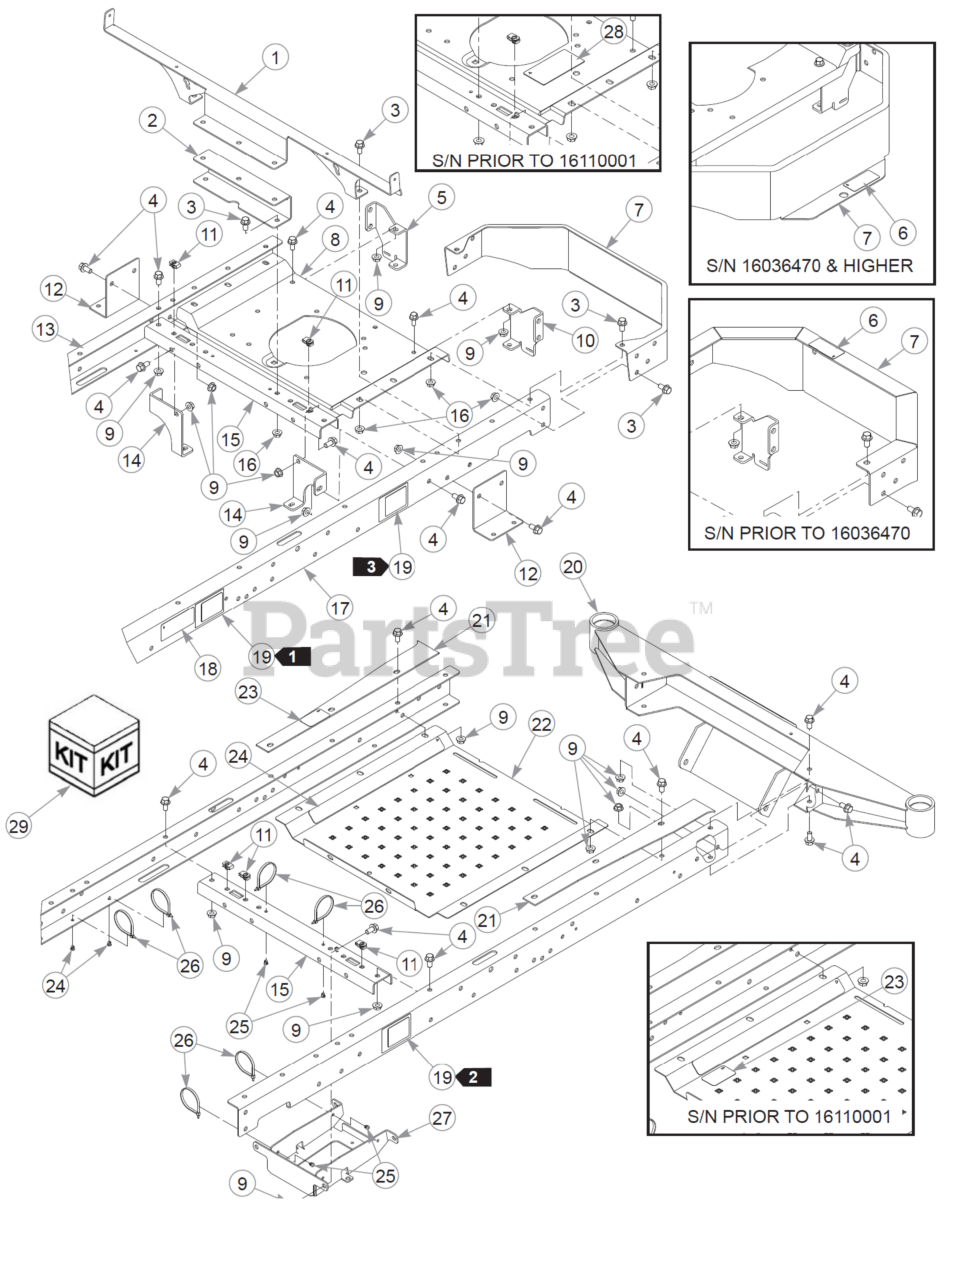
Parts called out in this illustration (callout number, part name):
1	SEAT SUPPORT
2	SPRING SUPPORT
3	CS .375-16X0.75 HXF G5ZN
4	KIT SWITCH
5	ORDER 125255 KIT
6	DECAL, HOT
7	S/C TO 556499
8	SVC, ENGINE PLATE
9	NT .375-16 HXFLK PLN
10	ORDER 125255 KIT
11	CN .250-20X .150 MAX THK
12	ORDER 125255 KIT
13	SVC, RS FRM CHNL
14	ORDER 125255 KIT
15	SVC, CROSS SUPPORT
16	NT .375-16 FLKG5
17	SVC, LS FRM CHNL
18	DECAL, ENGINE COMPART
19	Not Applicable
20	FRONT CROSS FRAME W/A
21	SVC, FAIRING
22	SVC, FOOT PAN
23	DECAL, LEVEL FUEL BLOWM
24	DECAL, SAFE OPERATE-GRAY
25	MOUNT, PUSH BUTTON
26	WIRE TIE, SMALL/SHORT
27	BATTERY TRAY
28	DECAL, PUMP BELT WARNING
29	KIT, HYDRO BRACKETS
